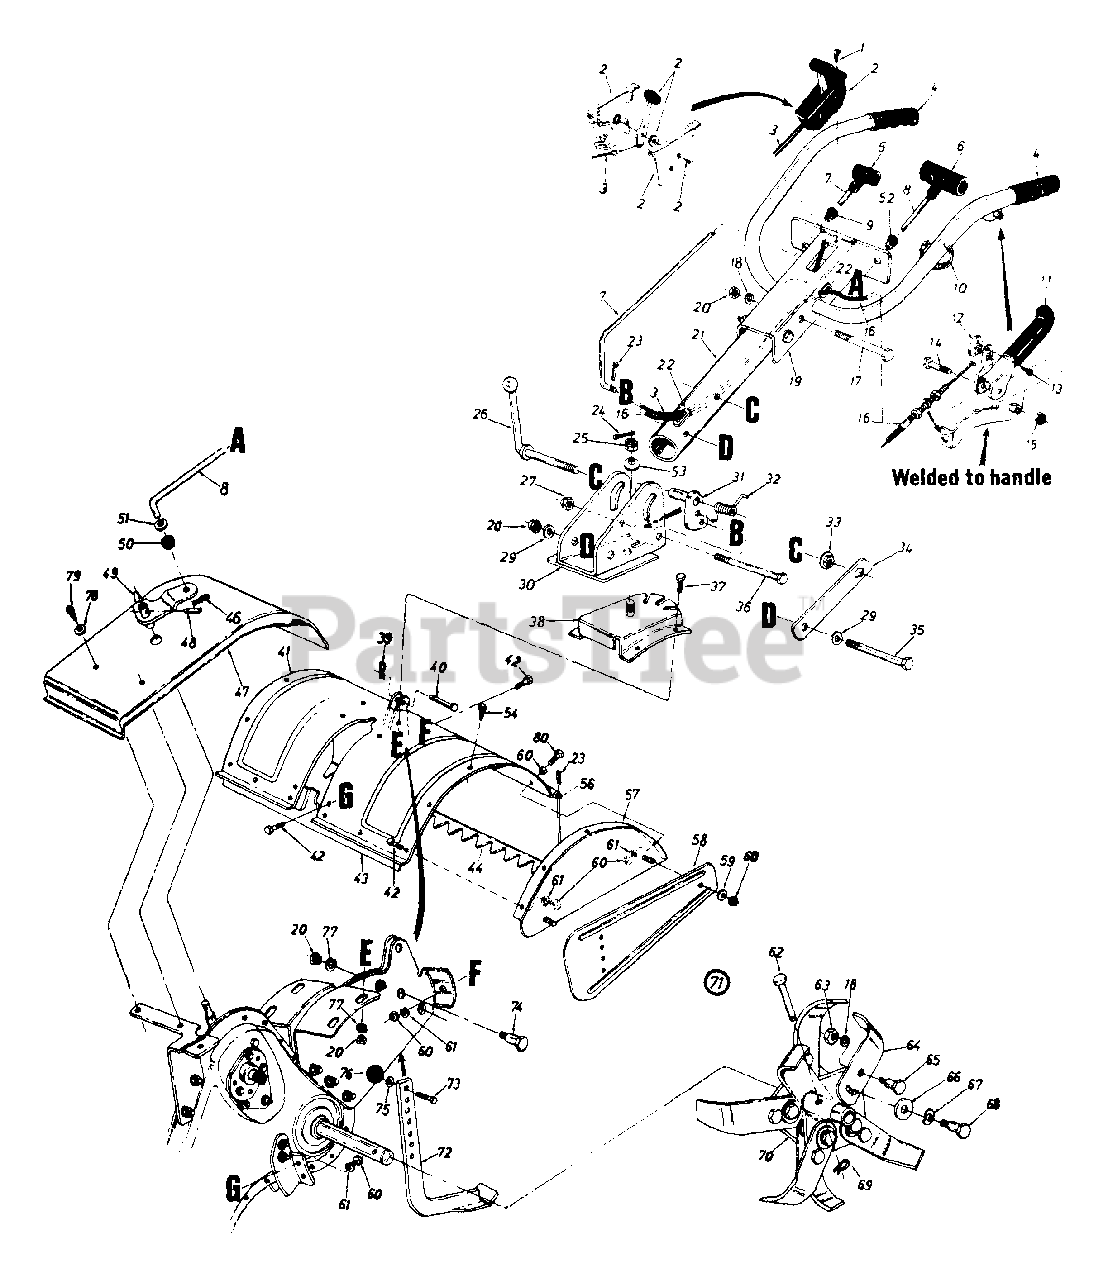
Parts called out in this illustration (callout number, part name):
1	Truss Mach. AS-Tap. Scr. #10 x .50" Lg.
2	Throttle Control Box Ass'y.
3	Throttle Control Wire
4	Handle Grip
5	Small "T" Knob
6	Large "T" Knob
7	Clutch Rod
8	Control Rod 37" Lg.
9	Snap On Bushing 3/8" Dia.
10	Cable Tie-Self Clinching
12	Barrel Cable Hold Down
13	Hex B-Tap Scr. #10 x .44 Lg.
14	Hex Bolt 3/8-24 x 2.25" Lg.
15	Hex Jam L-Nut 3/8-24 Thd.
16	Clutch Control Cable 46" Lg.
17	Hex Bolt 3/8-16 x 3.00" Lg.
18	L-Wash. 3/8" I.D.- H.D.
23	Cotter Pin 3/32" Dia. x .75" Lg.
24	Cotter Pin 3/32" Dia. x 1.25" Lg.
25	Hex Slotted Nut 5/8-18 Thd.
26	Handle Adj. Crank
27	Hex Cent. L-Nut 3/8-16 Thd.
29	Bell-Wash..4" I.D. x .87" O.D.
32	Spring Handle Adj.
33	Hex Flange Nut 3/8-24 Thd.
34	Bracket Hex Nut Retainer
35	Hex Bolt 3/8-16 x 3.25" Lg.
36	Hex Bolt 3/8-16 x 3.00" Lg.- Gr. 8
37	Hex Bolt 3/8-16 x 1" Lg."
40	Clevis Pin 375" Dia.
43	Bracket Reinforcement - 18"
46	Intern Cotter Pin 5/16" Dia.
49	Shifting Crank Ass'y.
50	Rubber Washer 33" I.D.
52	Snap On Bushing 1/2" Dia.
53	Bell-Wash..63" I.D x 1 25"
54	Hex Wash. Tap Scr.
56	Tiller Flap Rod
60	Hex Nut 5/16-18 Thd.
61	L-Wash. 5/16" I.D.
62	Clevis Pin .375" Dia.
63	Hex Nut 3/8-24 Thd.
65	Shld. Bolt 1/2" Dia. x .175
66	Fl-Wash..51" I.D. x 1.50"
67	Bell-Wash..515" I.D. x 1.14"
68	Shld. Bolt 1/2" Dia. x .320
69	Intern, Cotter Pin
73	Hex Bolt 3/8-16 x .75" Lg.
74	Shld. Bolt 1/2" I.D. x 62" Lg.
75	Fl-Wash. 3/8" I.D. x 5/8" O.D.
76	Ball Knob
77	L-Wash. 3/8" I.D.
78	Fl-Wash..281" I.D. x .62"
79	Hex Wash. Self-Tap Scr 1/4-20 x .50" Lg.
80	Hex Bolt 5/16-18 x 11/4" Lg.
